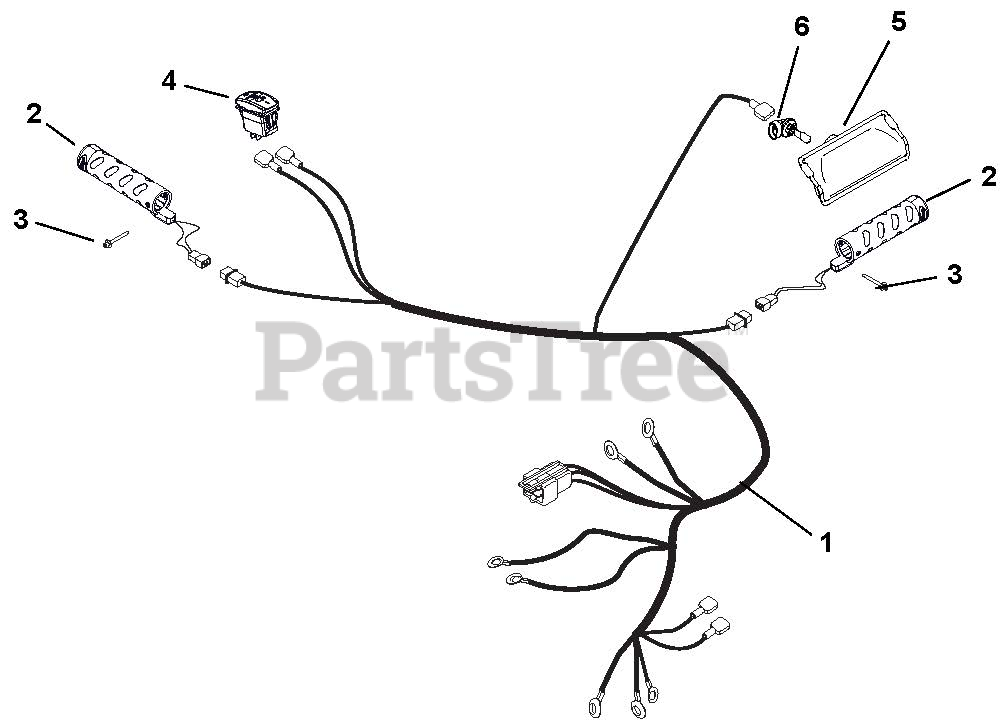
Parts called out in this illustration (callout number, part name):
1	HARNESS, LIGHT & WARMER
2	GRIP,HEATED HANDLE-GRAY
3	RVT-POP #43 .125X.313 STL ZINC
4	SWITCH,ROCKER SPST-ON/OFF
5	HEADLIGHT ASY, HALO 20W 2SHOT
6	BULB, LIGHT-HALOGEN 20W
